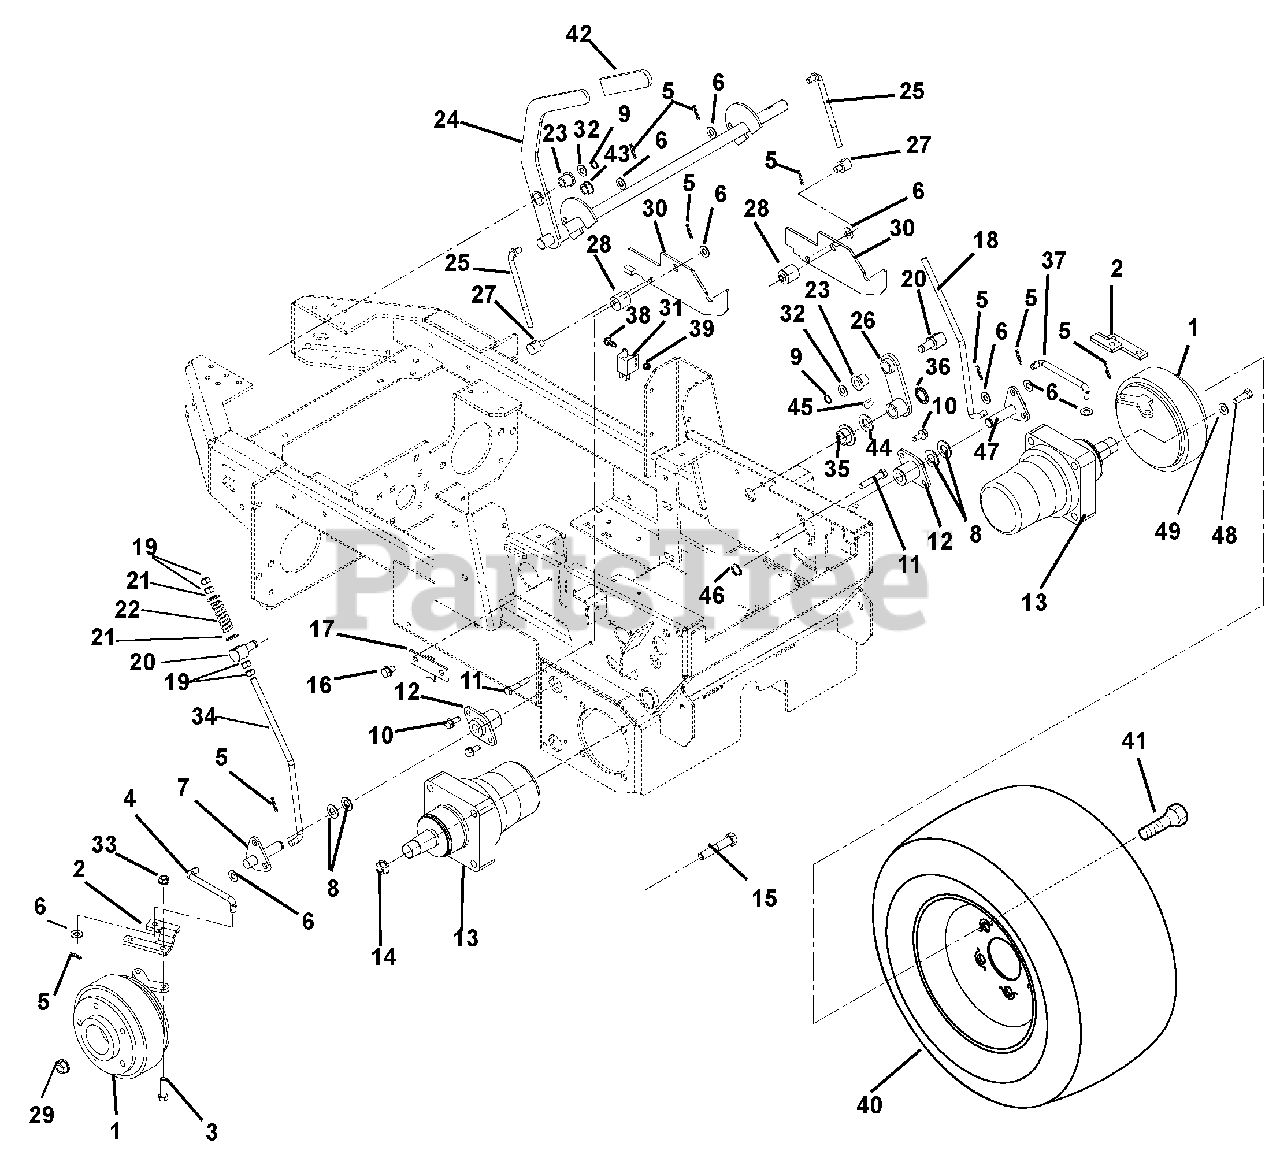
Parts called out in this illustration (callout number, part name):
1	Assembly, Brake
2	Extension, Brake
3	Bolt, Hex .31-18 x 1.00 Grade 5
4	Rod, Parking Brake Set Right Hand
5	Pin, Hair, Endries #25
6	Washer, Flat Steel .406 x .812 x .065
7	Weldment, Pivot (SN 000101 - 000499)
8	Washer, Flat-Steel .656 x 1.250 x .100
9	Ring, Retaining-External .500 x .050
10	Screw, Tapping .31-18 x .75 Hex Washer Head Thread
11	Bolt, Hex .31-18X1.75 Grade 5
12	Bushing, Flanged
13	Motor, Wheel TG 0280
14	Nut, .50-13 Nyloc Flange
15	Bolt, Wheel Motor .50-13 x 2.75
16	Screw, Tapping .38-16 x .50 Hex Washer Head Thread Rolling
17	Weldment, Parking Brake Hold Down
18	Rod, O.C. Left Hand Brake
19	Nut, Hex .38-16
20	Trunnion, Pivot .38
21	Washer, Flat-Steel .38 x .875 x .083 (SN 000101 - 499)
22	Spring, Compression (SN 000101 - 499)
23	Bushing, Flange .500 x .750 x .750 x 1.000 Bracket
24	Weldment, Parking Brake
25	Rod, Brake Link .375-24 UNF
26	Weldment, Brake Lever-Left Hand
27	Trunnion, .375-24 UNF
28	Spacer, Neutral Latch
29	Nut, Jam Center-Lock .75-16
30	Latch, Brake Lock
31	Switch, Double Pole N.O./N.O.
32	Washer, Hardened-Steel-THR.515 x .97 x .062
33	Nut, .31-18 Nyloc Flange
34	Rod, O.C. Right Hand Brake
35	Bushing, Flange .762 x 1.0 x .580 x 1.48 Nylon
36	Push Nut, .745 Shaft
37	Rod, Parking Brake Set Left Hand
38	Screw, Machine 10-24 x .75 Hex Washer Head
39	Nut, Locking-Nylon 10-24 with Insert
40	Tire/Wheel Assembly 24 x 12-12 (990100, 101)
41	Bolt, Lug Grade 8; .50-20 UNF x 1.38 LG; 60 Degree
42	Grip, Handle
43	Bushing, Split .75 x .81 x .20THK
44	Washer, Hardened-Thrust .758 x 1.23 x .031
45	Key, Woodruff .19 x .75 HRD#9
46	Ring, Retaining-External .625 x .050
47	Weldment, Pivot (SN 000101 - 000499)
48	Bolt, Hex .31-18 x 1.50 Gr 8
49	Washer, Locking .31 x .078 Regular
